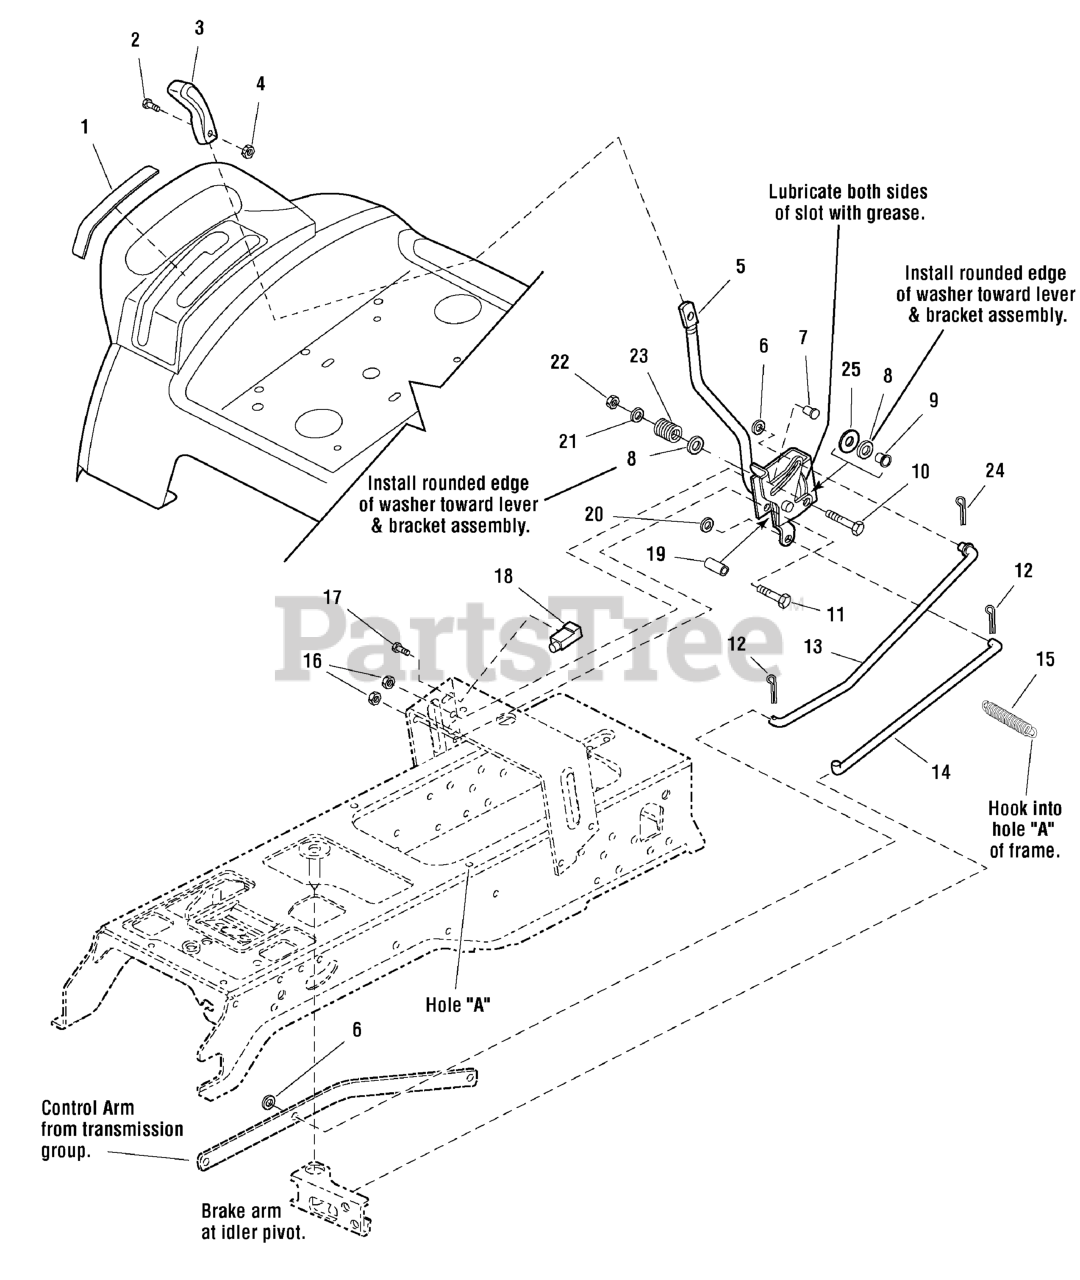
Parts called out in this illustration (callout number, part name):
1	DECAL, Cruise & Lift
2	SCREW, Torque Head Plus Socket Head, 1/4-20 x 7/8
3	KNOB, Cruise
4	NUT, Hex Lock ESNA Light, 1/4-20
5	LEVER & BRACKET ASSEMBLY, Cruise
6	WASHER, 3/8"
7	CARRIAGE BOLT, 5/16-18 x 3/4
8	WASHER, 9/16 x 1-1/4 x 1/8
9	SPACER, w/Flange, 11/32 x 15/32 x 3/4
10	CARRIAGE BOLT, 5/16-18 x 2 3/4
11	CARRIAGE BOLT, 5/16-18 x 2-1/4
12	PIN, Quick
13	ROD, Cruise
14	ROD, Return
15	SPRING, Cruise Return to Frame
16	NUT, Hex KEPS, 5/16-18
17	CAPSCREW, Hex Washer Head Plastite, 10-14 x 5/8
18	SWITCH, Push, Neutral Start, Gray
19	SPACER, 11/32 x 5/8 x 1-13/32
20	WASHER, 5/16
21	WASHER, 5/16, Black
22	NUT, Hex Lock ESNA Light, 5/16-18
23	SPRING, Compression
24	PIN, Cotter
25	DISC, Friction
